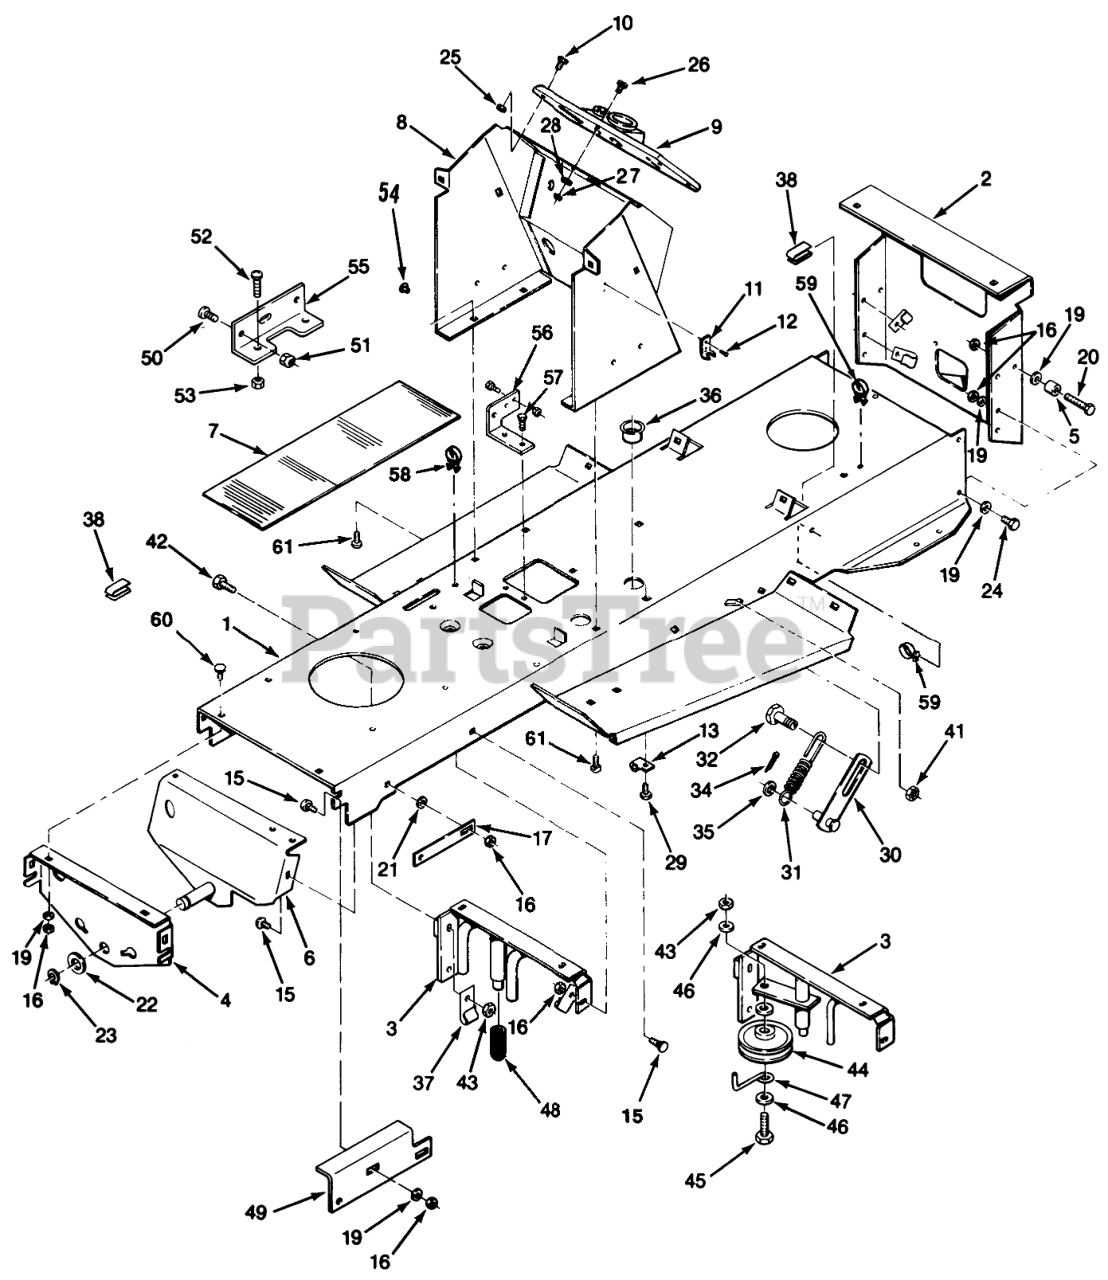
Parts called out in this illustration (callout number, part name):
1	FRAME R
2	PLATE-DRAWBAR R
3	ASS'Y-FRAME SUPPO R
4	PLATE SUPT - AXLE R
5	BEARING-CAM ROLLER
6	ASS'Y-AXLE SPT RE R
7	PAD-FOOTREST
8	WLDMENT-HOODSTAND B
9	CONSOLE
10	SCREW #10X.62 PHCR
11	KEEPER-LATCH
12	POPRIVET 1/8X 1/8 BK
13	J-CLIP
15	SCREW-CARR
16	NUT-LOCK, NI
17	STRAP R
18	Bolt
19	WASHER-PLAIN
20	SCREW-HH
21	WASHER-LOCK, INTERNAL
22	WASHER
23	RING-RETAINING
24	SCREW-HH
25	Nut
26	Screw
27	NUT-HEX
28	WASHER-LOCK
29	Bolt
30	ASSY LINK B
31	SPRING
32	CAM-ADJUST
34	PIN-COTTER
35	WASHER
36	BUSHING-NYLON 1.093
37	CLIP
38	RETAINER
40	Bolt
41	NUT-HEX, JAM
42	SCREW-HH
43	NUT-LOCK, NI
44	IDLER PULLEY R
45	SCREW-HH
46	WASHER-FLAT
47	RETAINER BELT R
49	BRACKET R.H. R
50	Screw
51	NUT-LOCK, NI
52	Screw
53	Nut
54	PLUG-NYLON .250
55	BRKT-FUSE HOLDER B
56	BRKT-SWITCH R
57	Screw-Machine
58	CLIP-SNAP IN
59	CLIP-SNAP IN
60	CARRIAGE BOLT -4
61	Bolt
